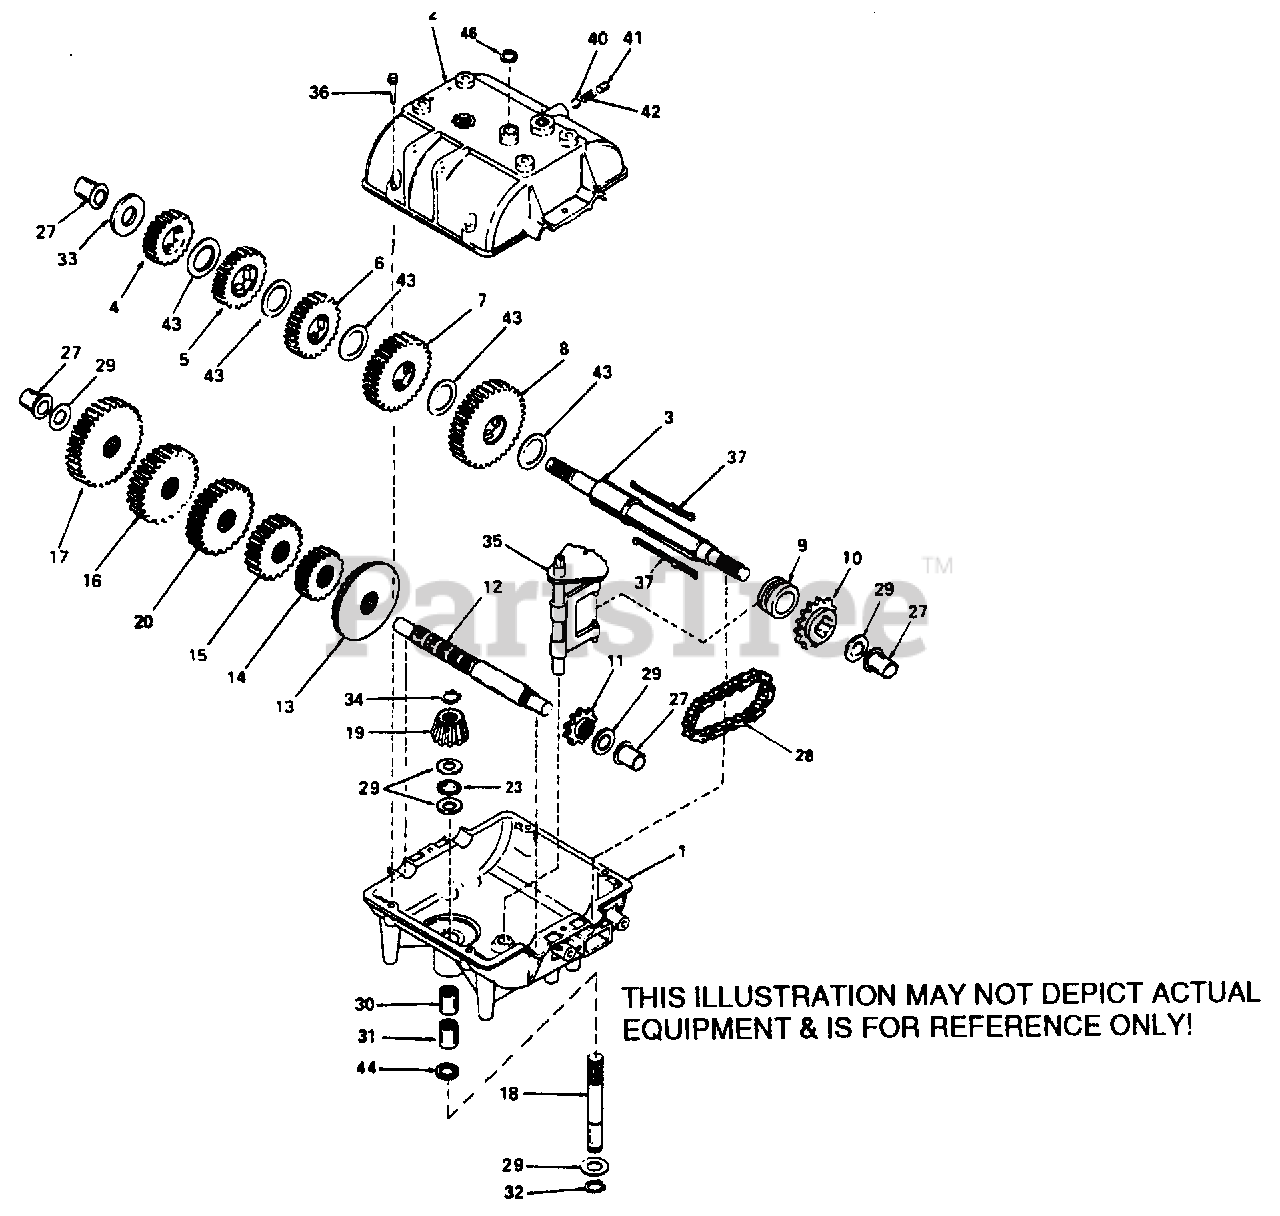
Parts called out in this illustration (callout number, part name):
1	CASE, TRANSMISSION
2	COVER, TRANSMISSION
3	SHAFT, OUTPUT & BRAKE
4	KEY SWITCH(INCLUDES HARDWARE)
4	GEAR, SPUR(25 TEETH)
5	GEAR, SPUR(30 TEETH)
6	GEAR, SPUR(32 TEETH)
7	GEAR, SPUR(35 TEETH)
8	GEAR, SPUR(37 TEETH)
9	COLLAR, SHIFT
10	SPROCKET(18 TEETH)
11	SPROCKET(9 TEETH)
12	SHAFT, COUNTER
13	GEAR, BEVEL(42 TEETH)
14	GEAR, SPUR(12 TEETH)
15	GEAR, SPUR(15 TEETH)
16	GEAR, SPUR(20 TEETH)
17	GEAR, SPUR(25 TEETH)
18	RUBBER PAD
18	SHAFT, INPUT
19	BEVEL PINION, INPUT
20	GEAR, SPUR(18 TEETH)
23	BEARING, THRUST
27	BUSHING, FLANGED
28	CHAIN, ROLLER(NO.41 CHAIN, 24 LINKS)
29	WASHER, THRUST
30	BEARING, NEEDLE
31	BEARING, NEEDLE
32	RING, RETAINING
33	WASHER, THRUST
34	RING, RETAINING
35	ROD & FORK ASSY., SHIFT
36	SCREW, FLANGED HEX HEAD THREAD, 1/4-20 X
40	BALL, STEEL, 5/16"
41	SCREW, SET 3/8-16 X 3/8"
42	SPRING
43	WASHER, THRUST
44	"O" RING
46	SEAL, SQUARE CUT
